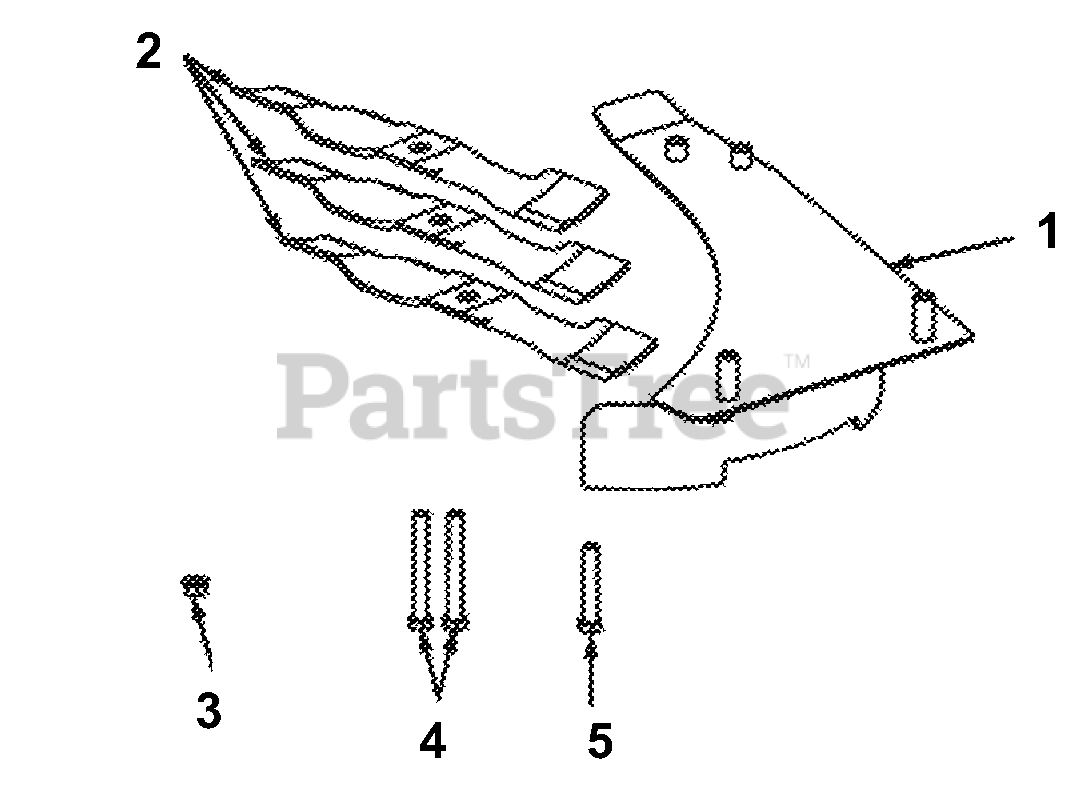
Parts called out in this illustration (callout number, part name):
1	Mulching Baffle
2	Mulching Blade
3	Hex Flange Nut 3/8-16
4	Hex Cap Screw 3/8-16 x 2.75
5	Hex Cap Screw 3/8-16 x 1.75
